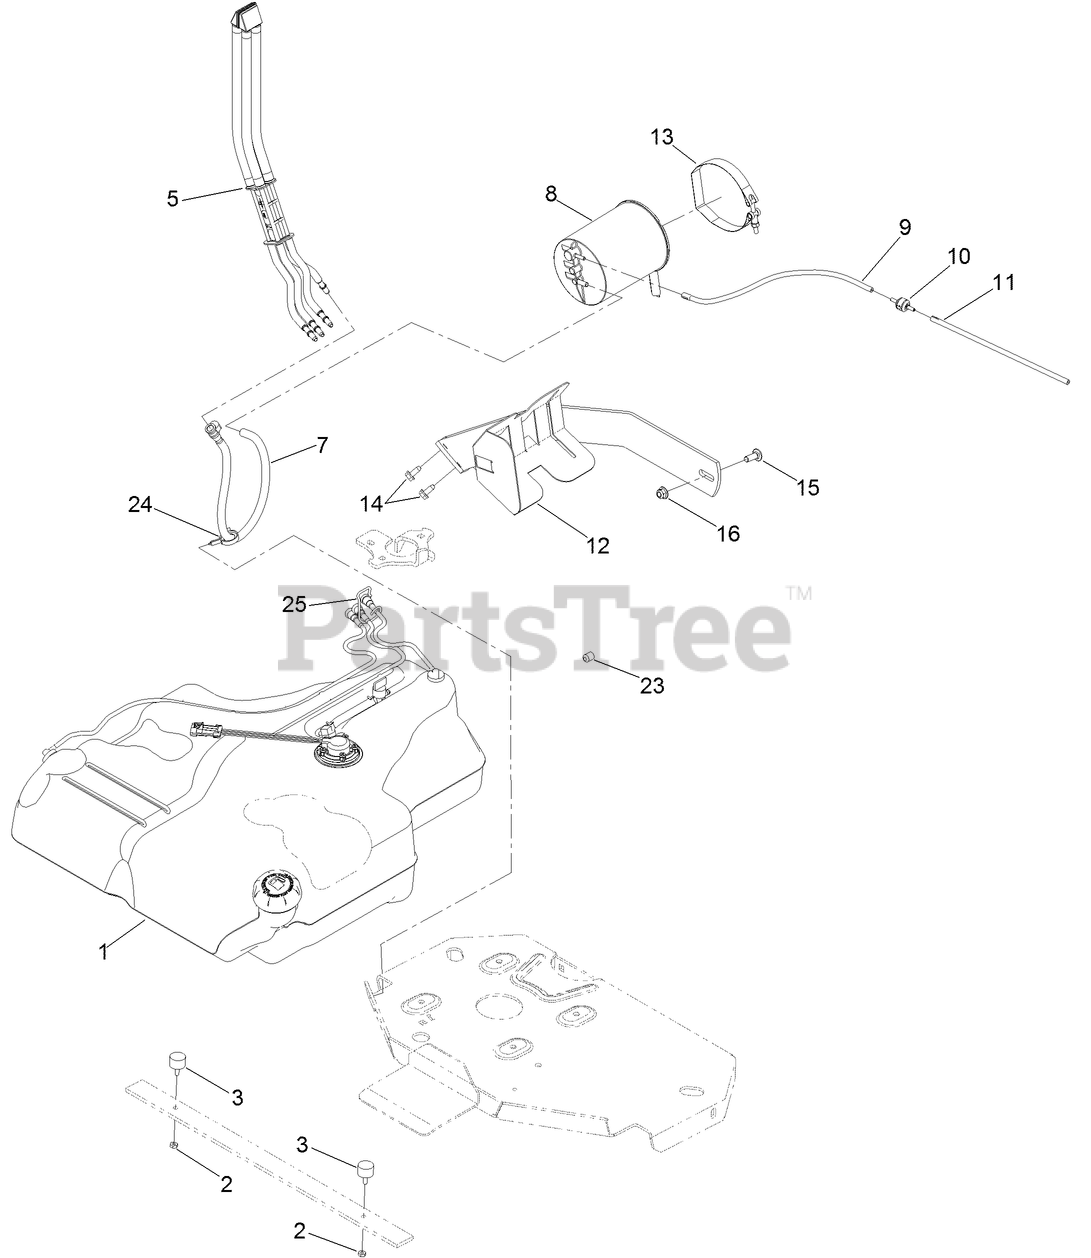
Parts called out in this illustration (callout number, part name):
1	FUEL TANK ASM
2	NUT-JAM
3	BUMPER-RUBBER (W/ STUD)
5	FUEL MANIFOLD VENT ASM
7	VENT HOSE ASM
8	CANISTER-CARBON, 1200CC
9	HOSE-VENT, FORMED
10	VALVE-CHECK, VACUUM
11	HOSE-VENT, FORMED
12	MOUNT-CANISTER
13	CLAMP-T-BOLT
14	SCREW-HWHTF
15	SCREW-CARR
16	NUT-HF, NI
23	PLUG-PORT
24	CLAMP-HOSE
25	RETAINER-LINE, VAPOR
